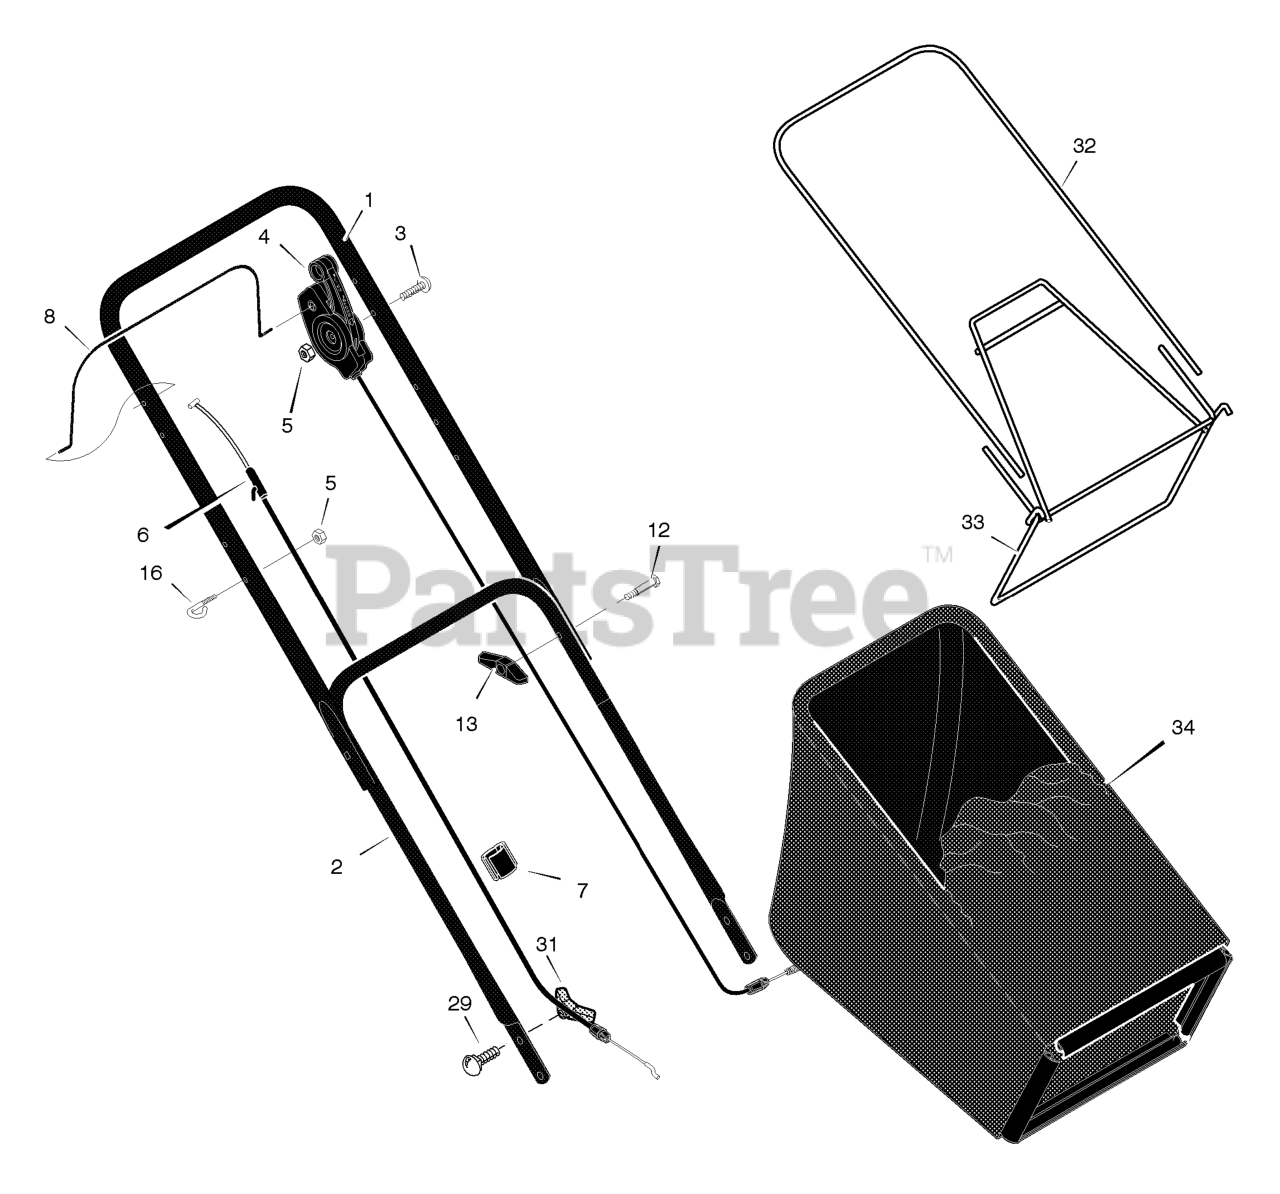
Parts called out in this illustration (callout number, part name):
1	Handle, Upper
2	Handle, Lower
4	Control, Drive
5	Locknut
6	Cable, Stop
7	Fastener, Cable
8	Lever, Stop
13	Knob
16	Guide, Rope
29	Bolt, Carriage
31	Knob, Plastic
32	Tube, Bag
33	Frame Assembly
34	Bag, Cloth
